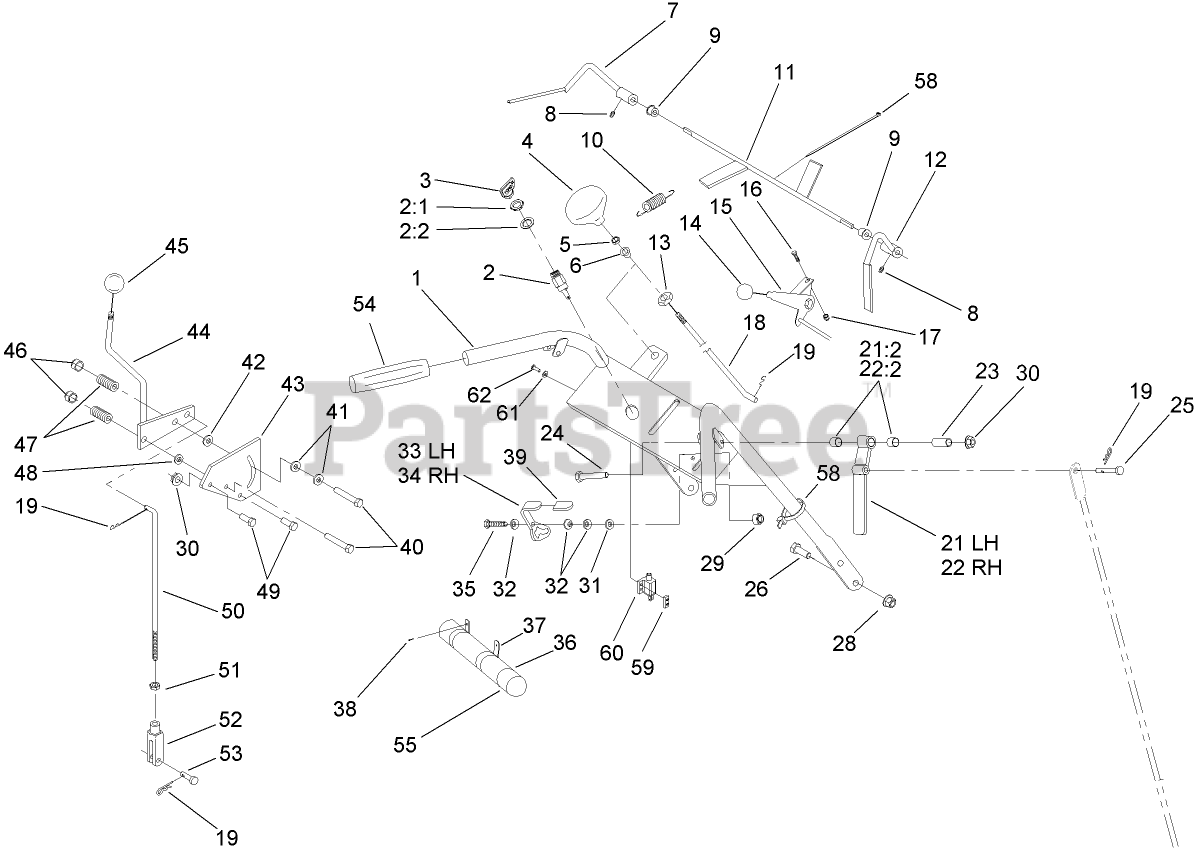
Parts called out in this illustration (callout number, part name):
1	HYDRO HANDLE ASM
2	SWITCH-ON / OFF
2:1	NUT-HH
2:2	WASHER-TOOTH, INTERNAL
3	KEY-IGNITION
4	Knob-Push / Pull
5	NUT-JAM
6	Bearing-Nylon
7	LH OPERATOR PRESENCE CONTROL LEVER ASM
8	SCREW-SET
9	BUSHING-NYLON
10	SPRING-EXTENSION
11	ROD-CONTROL, OPERATOR PRESENCE
12	RH OPERATOR PRESENCE CONTROL LEVER ASM
13	NUT-PUSH
14	KNOB-BALL
15	THROTTLE CABLE ASM
16	BOLT-CARR
17	NUT-LOCK, NI
18	Linkage-Blade
19	PIN-COTTER
21	LH Drive Lever ASM
21:2	BUSHING-SLEEVE
22	RH Drive Lever ASM
22:2	BUSHING-SLEEVE
23	Bushing-Lever, Drive
24	SCREW-HH
25	Pin-Clevis
26	SCREW-HHF
28	NUT-HF
29	NUT-LOCK, NI
30	NUT-HF
31	WASHER-FLAT
32	WASHER-SPRING
33	LH LATCH GRIP ASM
34	RH LATCH and GRIP ASM
35	SCREW-HH
36	TUBE-MANUAL
37	CLAMP-R
38	SCREW-HWHTF
39	GRIP-LATCH
40	SCREW-HH
41	Washer-Friction
42	Washer-Friction
43	PLATE-LEVER, SHIFTER
44	LEVER-SHIFT
45	KNOB-BALL
46	NUT-LOCK, NI
47	SPRING-COMPRESSION
48	WASHER-PLAIN
49	SCREW-HH
50	Rod-Control, Speed
51	NUT-JAM
52	YOKE-ADJUSTABLE
53	PIN-CLEVIS
54	GRIP-FOAM
55	CAP-HOUSING
58	TIE-CABLE
59	PLATE-TAPPED
60	SWITCH-OPEN, NORMALLY
61	WASHER-FLAT
62	SCREW-PPH
